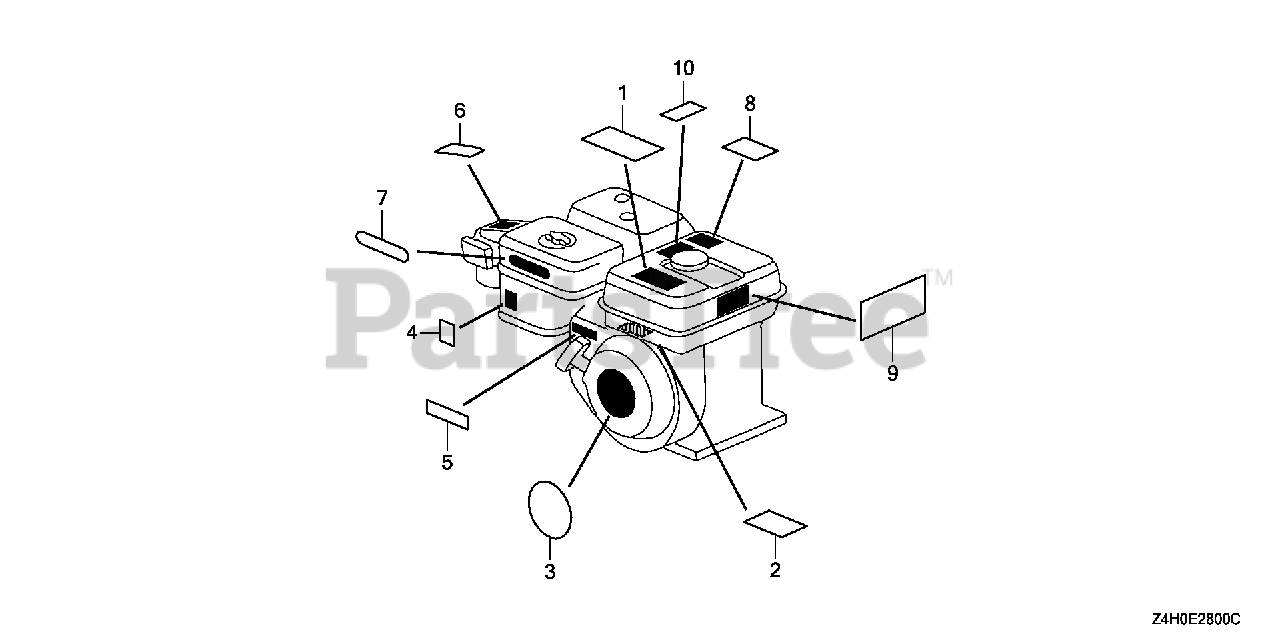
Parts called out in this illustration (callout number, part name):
3	EMBLEM (GX120)
4	MARK, CHOKE
5	MARK, THROTTLE INDICATION
9	MARK, OPERATOR CAUTION (ENGLISH)(MADE IN THAI)
10	MARK, EX. CAUTION (ENGLISH)
